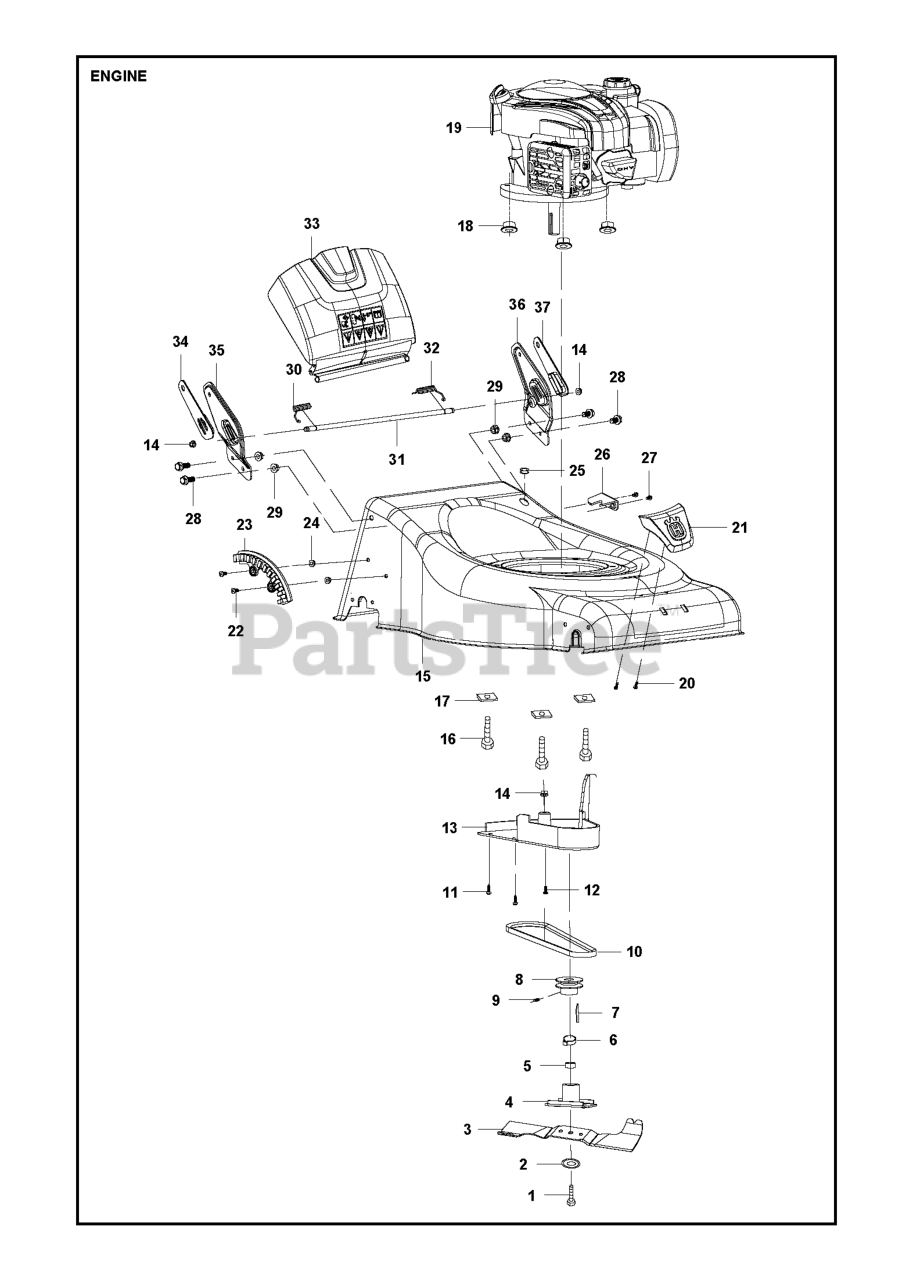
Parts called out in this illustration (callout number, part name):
12	SCREW M6*16 #26800204601
14	LOCK NUT M6,GB/T6187.1-2000 #2
18	LOCKING BOLT M8,GB6187.1 #2680
23	SEGMENT #25214200102
25	COVER #25217800104
27	BOLT M6*12,(GB5787-86)GB6674.1
28	BOLT M8*16 #26800606401
30	SPRING #26801125501
32	BRACKET #26801125401
34	PLATE RIGHT
35	BRACKET RH
37	PLATE LEFT
